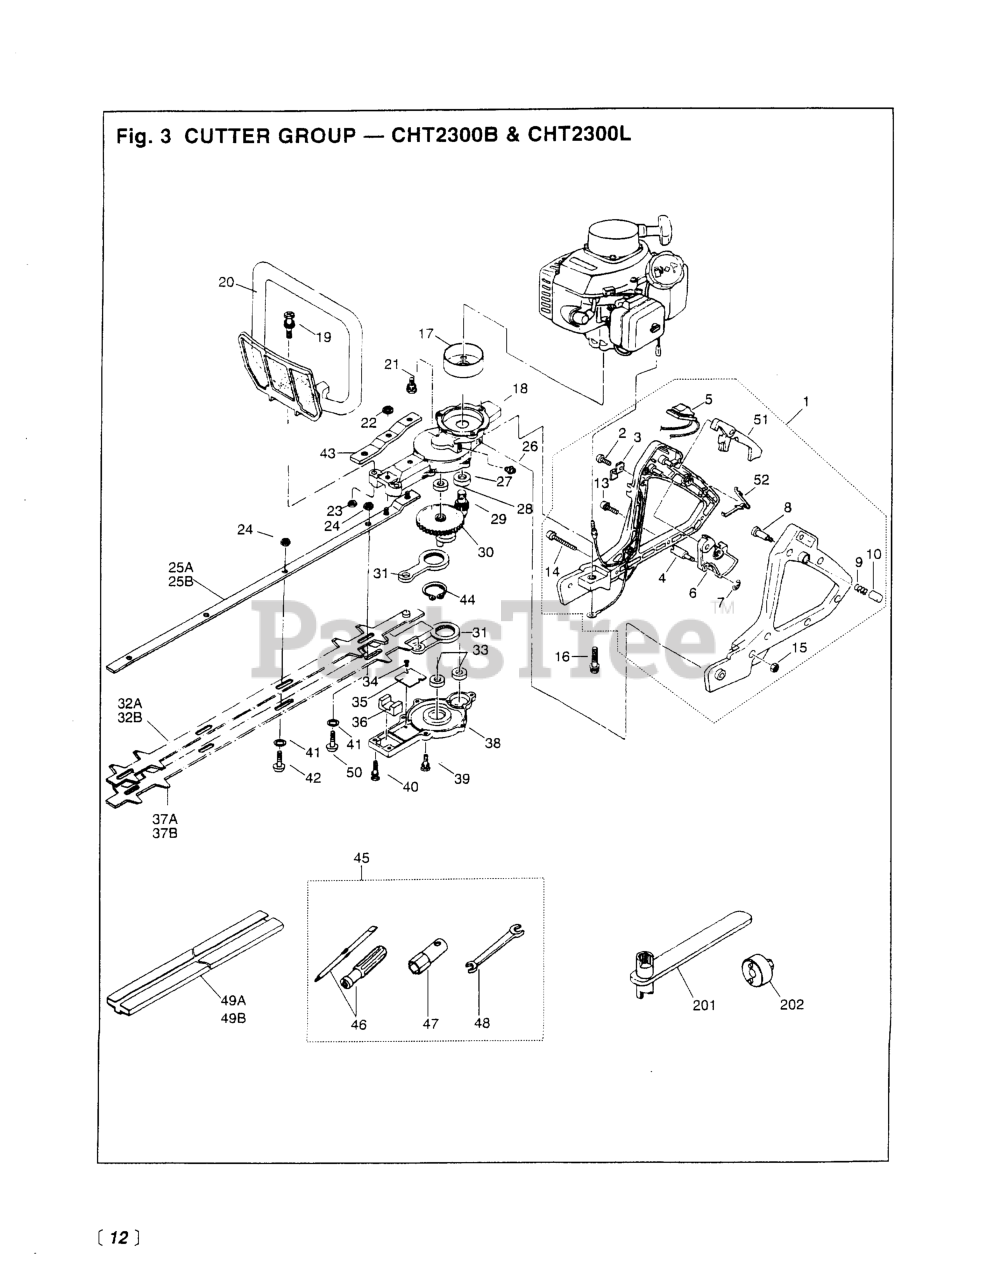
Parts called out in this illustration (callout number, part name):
1	HANDLE, REAR ASSY (RPL 3873-)
2	SCREW, M4 x 10
3	PLATE
4	END, CABLE
5	SWITCH
6	LEVER, THROTTLE (RPLS -13220)
7	RING, SNAP
9	SPRING
10	CAP, PIN
13	NUT, M6 X 4
14	BOLT, M6 X 50
15	NUT, M6 X 5
16	BOLT, M6 X 40
17	DRUM, CLUTCH
18	CASE, MIDDLE (RPLS -11110)
20	HANDLE (RPLS -12101)
21	BOLT, M6 X 14
22	NUT
23	NUT, M6 X 5
24	NUT, M6
25B	PLATE, GUIDE (RPLS -11611) 30
26	FITTING, GREASE
27	BEARING
28	BEARING
29	PINION
30	GEAR COMPLETE
31	ROD
32B	BLADE, UPPER DOUBLE 30
33	BEARING
34	SCREW, M3 x 5
35	PLATE
36	FELT
37B	BLADE, LOWER DOUBLE 30
38	CASE, LOWER
39	BOLT, M5 x 16
40	BOLT, M5 X 20
43	PLATE (RPLS 3880-11130)
44	RING, SNAP, M25 X 1.2
45	TOOL SET
46	SCREWDRIVER
47	SOCKET, HEX, 3/4
48	SPANNER, 8 X 10 (RPLS 2540- )
49B	COVER, BLADE (30
202	WRENCH (TOOL)
NI	SCREW, M4 X 16
NI	SCREW, M4 x 30
